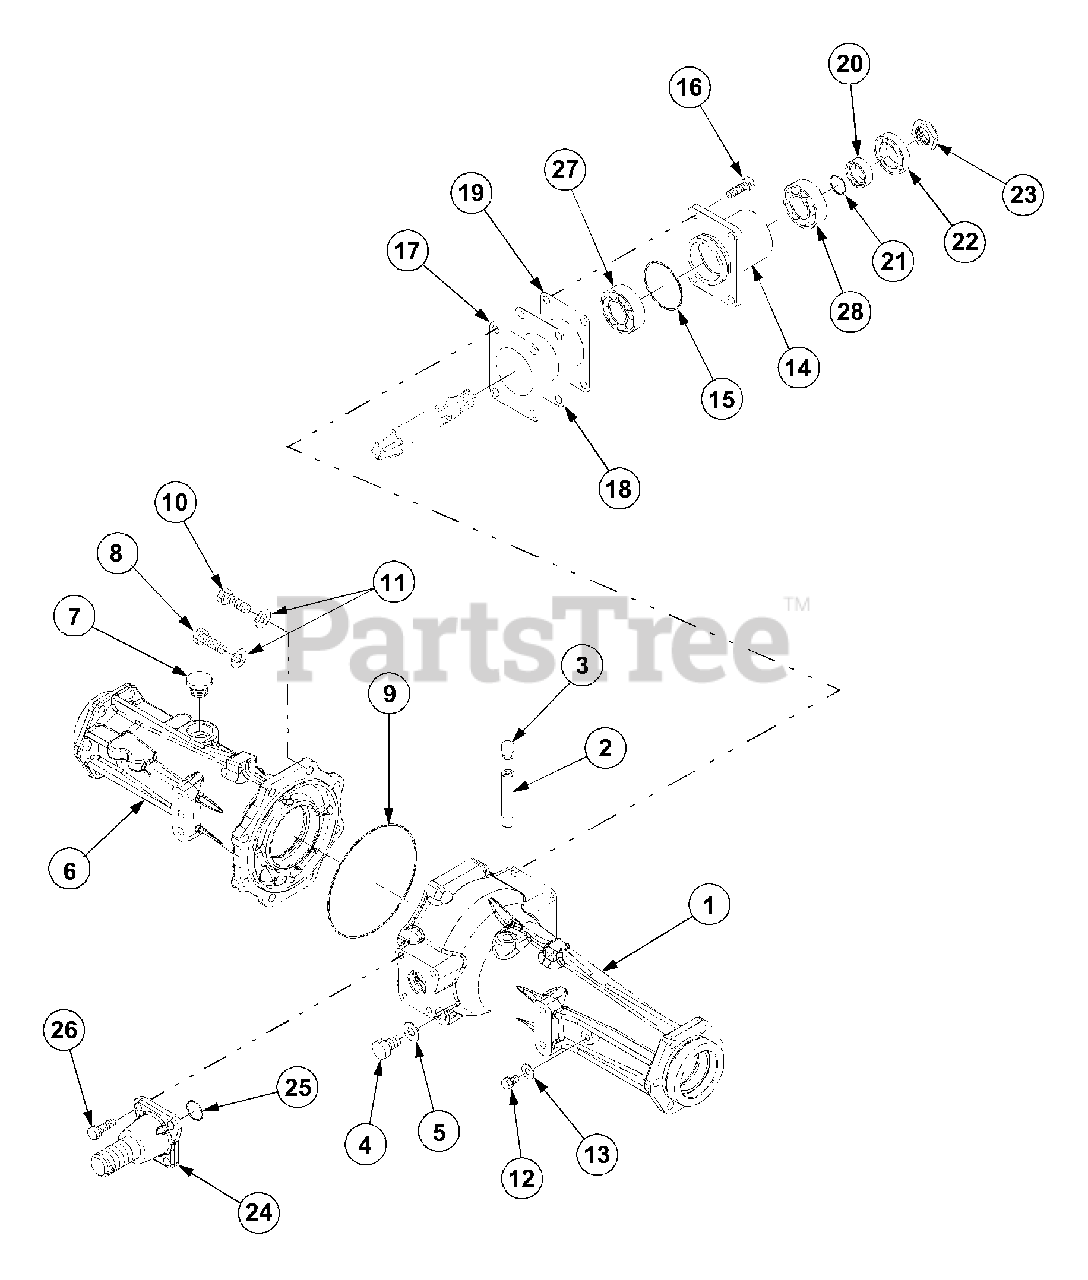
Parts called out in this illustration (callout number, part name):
1	Case A,Center
2	Pipe
5	Washer,Seal
6	Case B,Center
11	Washer,Spring
14	Case,Front Axle
16	Bolt,w/Washer
26	Bolt,w/Washer
27	Bearing,Roller
28	Bearing,Taper
